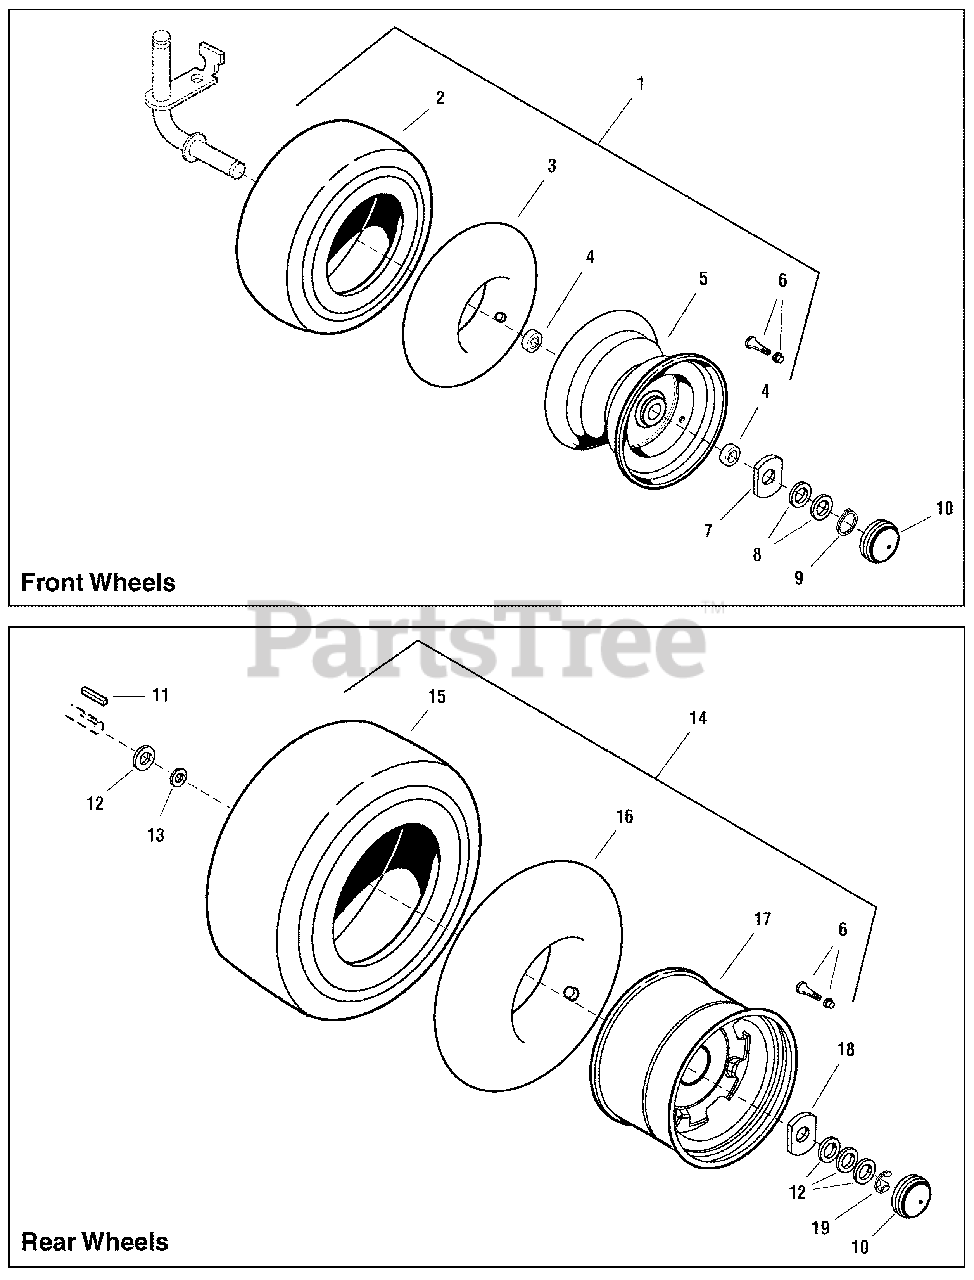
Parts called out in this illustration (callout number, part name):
1	WHEEL & TIRE ASSEMBLY, Front, (Includes Ref. Nos. 2, 3, 4, 5, & 6)
2	TIRE, 15 x 6, Super Turf
3	TUBE, Tire, Front, 4.10/3.50
4	BEARING, Ball
5	WHEEL, 4-1/2" x 6"
6	VALVE STEM & CAP ASSEMBLY
7	WASHER, Special
8	WASHER, 1
9	RING, Retainer
10	CAP, Hub, Gray
11	KEY, Parellel, 3/16 x 3/16 x 1-1/2
12	WASHER, 3/4
13	WASHER, 3/4 x 1-1/16 x 5/64
14	WHEEL & TIRE ASSEMBLY, Rear, (Includes Ref. Nos. 6, 15, 16 & 17)
15	TIRE, 22 x 10, 10 Super Turf
16	TUBE, Tire, 20 x 8, Rear
17	WHEEL, 7 x 9.97 Dia. 3/4 ID, Hub
18	WASHER, Special
19	RING, "E" External
